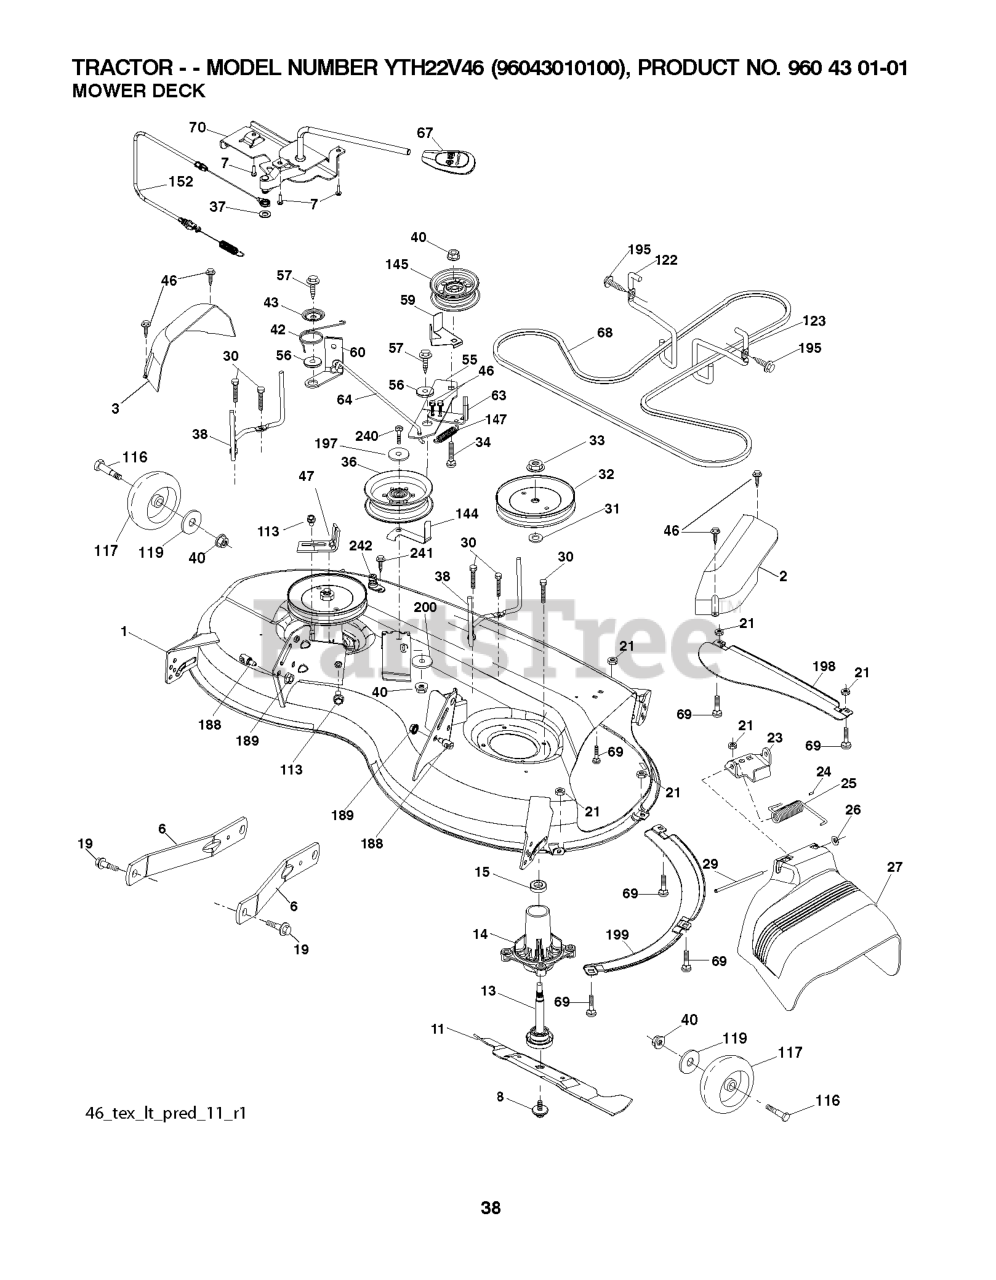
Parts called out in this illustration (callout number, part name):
1	DECK.WELDMENT.46"
2	COVER.MANDREL.RH.46"
3	COVER.MANDREL.LH.46"
6	ARM.SUSPENSION.MOWER.R
7	SCREW.#10 X 0.750.BOS
8	BOLT.WASHER.ASM.7/16-2
11	BLADE.MOWER.46".HI.LIFT
13	SHAFT.ASM.MDRL.N/GREASE.38
14	RP.HOUSING.MANDREL.4PT.
19	BOLT.SHOULDER
21	LOCKNUT
23	BRKT.DEFLECTOR.38"2005+
24	CAP-SLEEVE LT
25	SPRING.TORSION.DEFLECT
26	NUT PUSH M
27	SHIELD.DEFLECTOR.MOWER.46"BLAC
29	ROD.HINGE
30	SCREW, WASHER HEAD
31	WASHER.SPACER.MANDREL
32	PULLEY.MANDREL.5.438.PD
33	NUT.FLANGE.LOCK.TOP
34	BOLT.3/8-16X1.50
36	PULLEY.IDLER.2006
37	WASHER
38	KEEPER.BELT.LH.MANDREL
40	NUT LOCK FLG 3/8-16 UNC
42	SPRING.TORSION.BRAKE
43	SRPING.TORSION.RETAINE
46	SCREW.1/4-20X5/8
47	BRKT.CLUTCH.CABLE
56	SPACER.RETAINER
57	SCREW 3/8-16X1
59	GUARD, BELT
60	ARM BRAKE MOWER RH 38"
63	ARM BRAKE MOWER
64	LINKAGE BRAKE
67	HANDLE.CLUTCH.CABLE.LT
68	V-BELT
69	BOLT
70	CLUTCH.ASM.CABLE.HUSQ.TEX
113	BOLT.5/16HEX.WHS.HD
116	BOLT.SHOULDER.3/8-16X3-5/8.
117	RP WHEEL. GUAGE RALLY
119	WASHER
122	KEEPER BELT ENGINE LH
123	KEEPER BELT RH
144	KEEPER.BELT.MOWER
145	PULLEY.IDLER.48"PRIMARY
147	SPRING RETURN
152	CABLE CLUTCH MANUAL W/SPR.
188	STUD.FASTNER.W/ANTI-ROTATE
189	NUT LOCK HEX FLANGE 5/16-18
195	SCREW, 3/8-16X3/4
197	WASHER
198	BAFFLE CENTER FRONT
199	BAFFLE FRONT RH
200	WASHER.13/32 X 1 X 1/2.11GUARD
240	BOLT-HEX EAK
241	SCREW.TT.#10-32X.5.3/8.FLANGE
242	PORT.WASHOUT
